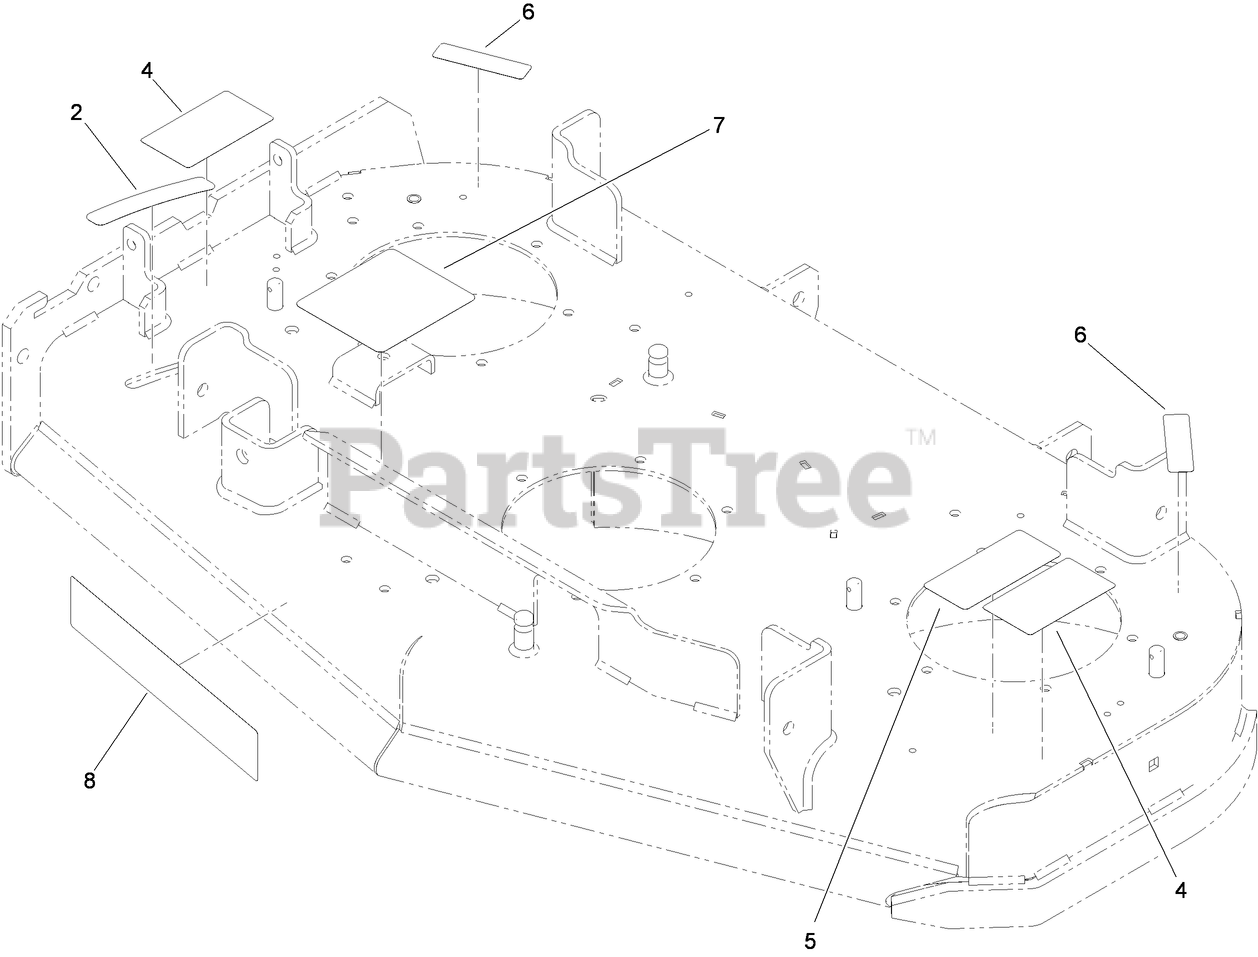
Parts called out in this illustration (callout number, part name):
2	DECAL-SETTING, BAFFLE
4	DECAL-DANGER
5	DECAL-TORQUE, BLADE BOLT
6	DECAL-DANGER
7	DECAL-ROUTING, BELT
